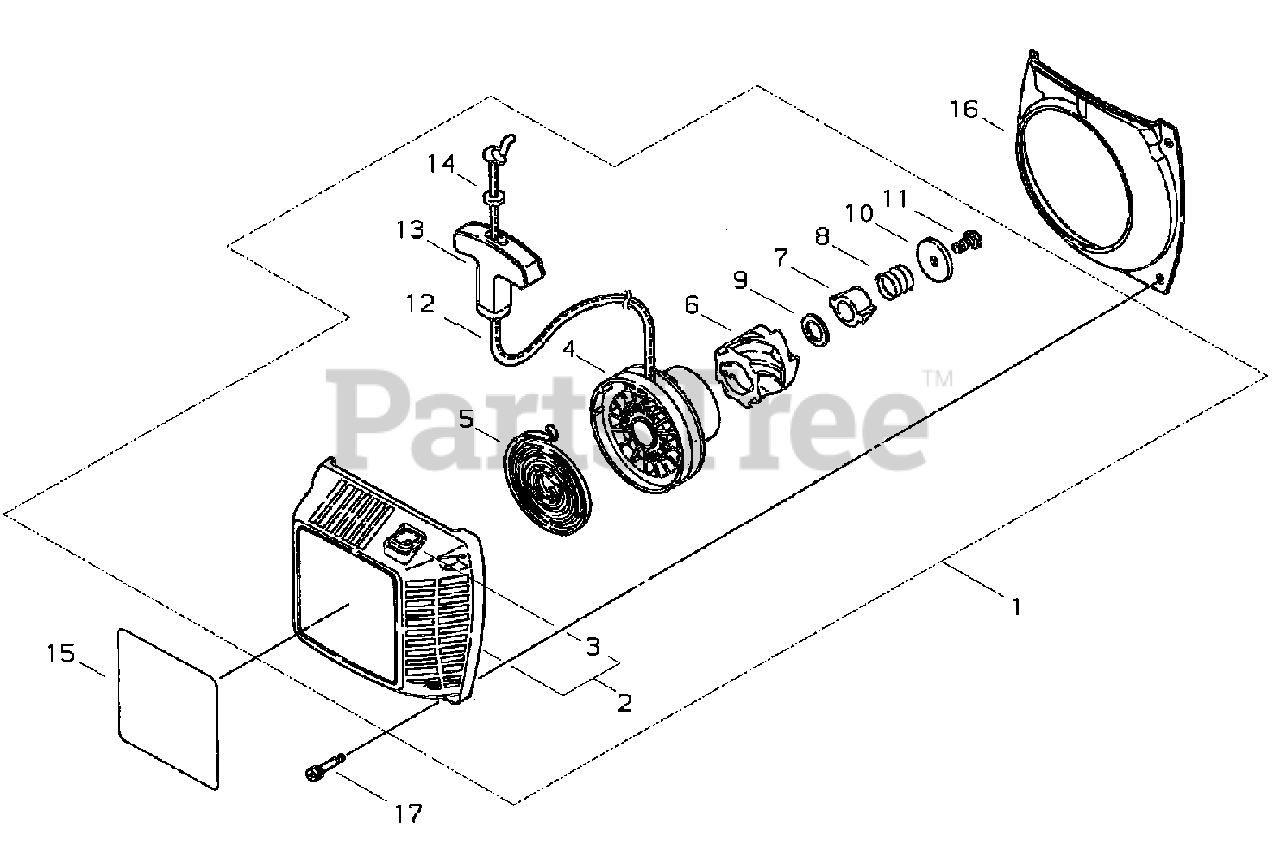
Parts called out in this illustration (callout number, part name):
1	STARTER ASSY
2	CASE, STARTER
3	GUIDE, ROPE
4	REEL, ROPE
5	SPRING, REWIND
6	RATCHET
7	CATCHER, PAWL
8	SPRING, FRICTION
9	WASHER, THRUST
10	WASHER
11	SCREW - 5
12	ROPE, STARTER
13	GRIP, STARTER
14	RETAINER, ROPE
15	LABEL - TRADE
16	PLATE, AIR
17	SCREW - 4X20
